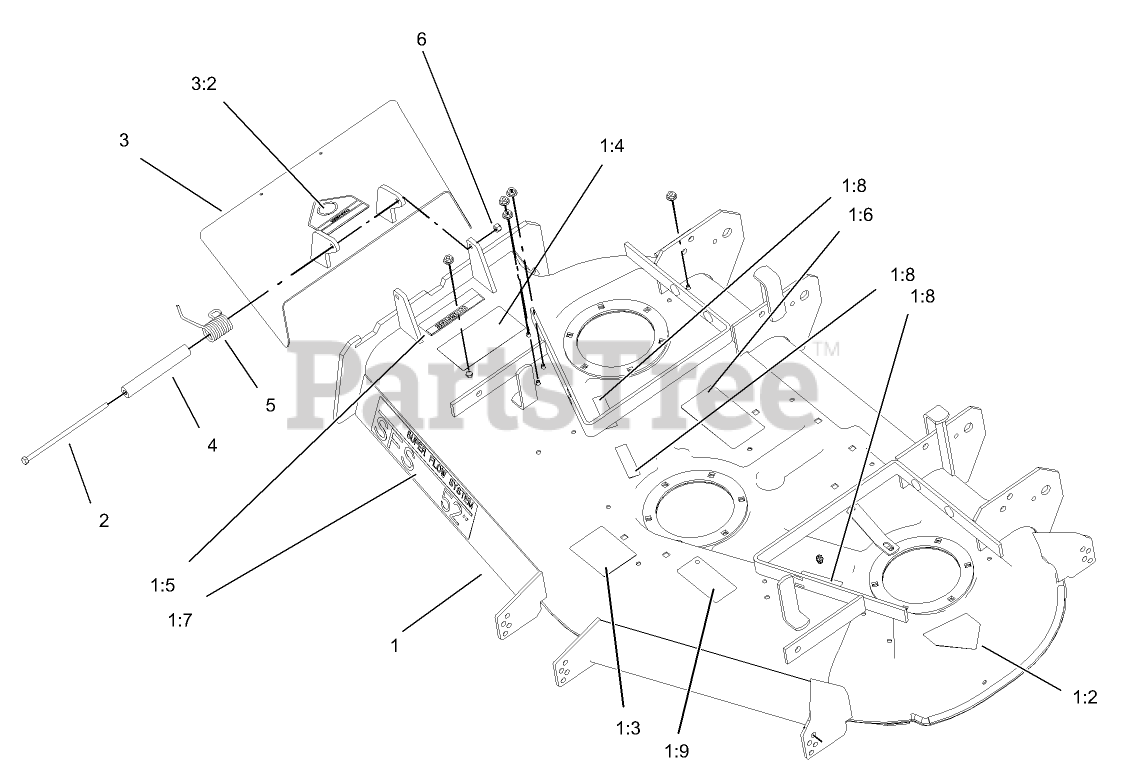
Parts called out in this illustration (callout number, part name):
1	Deck ASM
1:2	DECAL-DANGER
1:3	DECAL-WHEEL, GAGE
1:4	DECAL-DANGER, THROWN OBJECT
1:5	DECAL-WARNING
1:6	DECAL-BELT ROUTING
1:7	DECAL
1:8	DECAL-COVER, MISSING
1:9	DECAL-TORQUE, BLADE BOLT
2	SCREW-HH
3	Deflector ASM
3:2	DECAL-DANGER
4	SPACER
5	SPRING-TORSION
6	NUT-LOCK, NI
